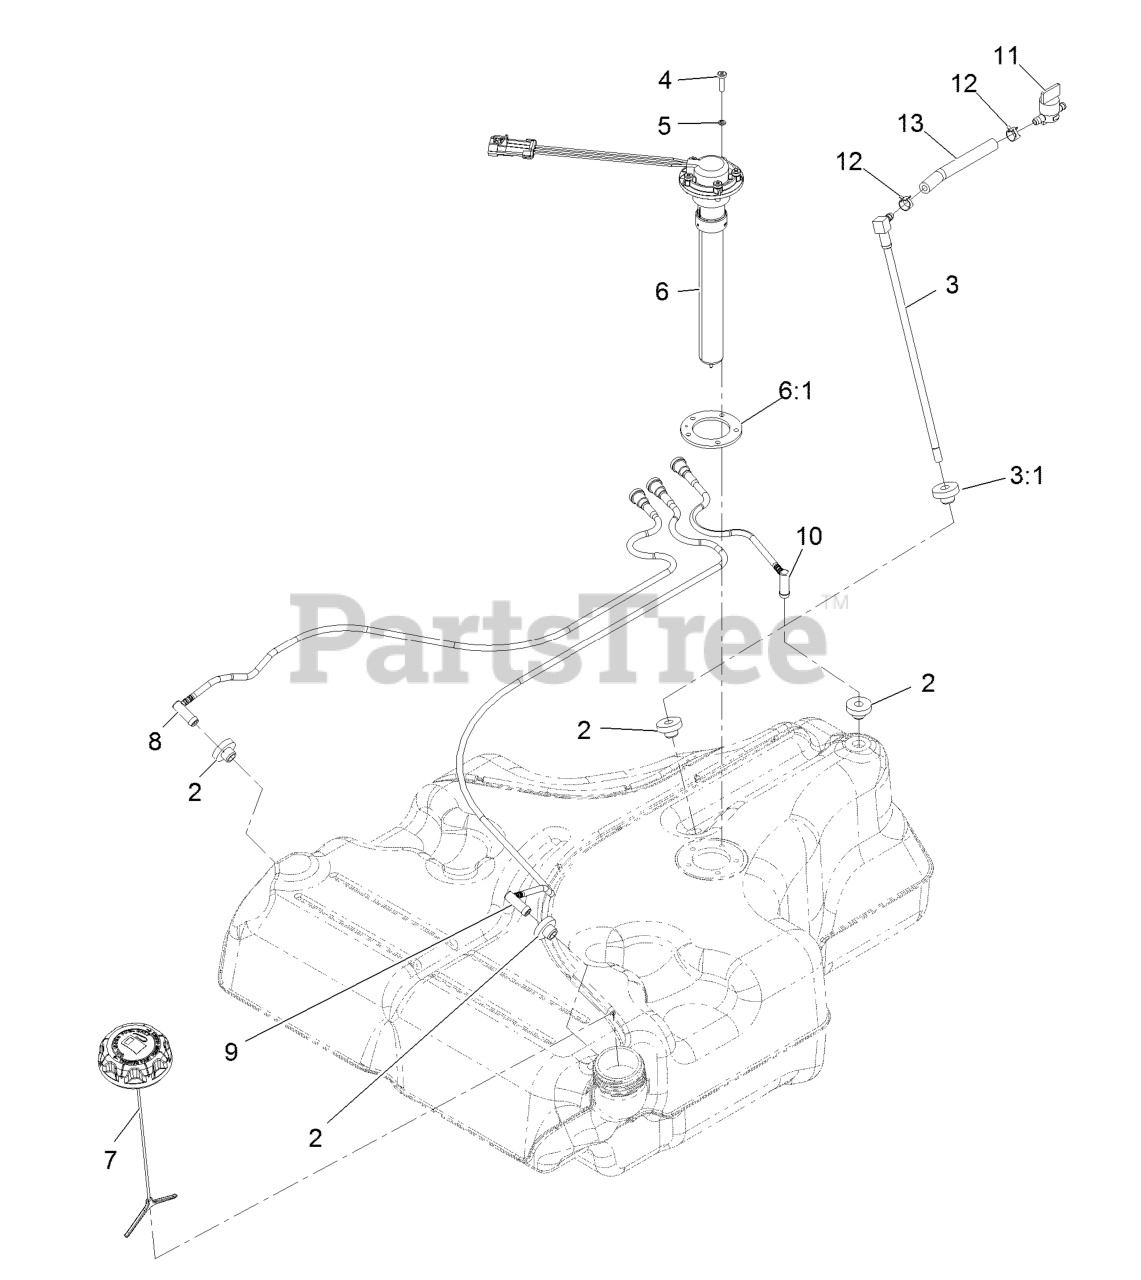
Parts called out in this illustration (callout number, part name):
2	BUSHING
3	FUEL LINE KIT (WITH GROMMET)
3:1	BUSHING
4	SCREW-PAN
5	WASHER-LOCK
6:1	GASKET-SENDER, FUEL
7	CAP-FUEL, RATCHETING
8	RH VENT LINE KIT (WITH GROMMET)
9	LH VENT LINE KIT (WITH GROMMET)
10	REAR VENT LINE KIT (WITH GROMMET)
11	VALVE-FUEL
12	CLAMP-HOSE
13	HOSE-FUEL
